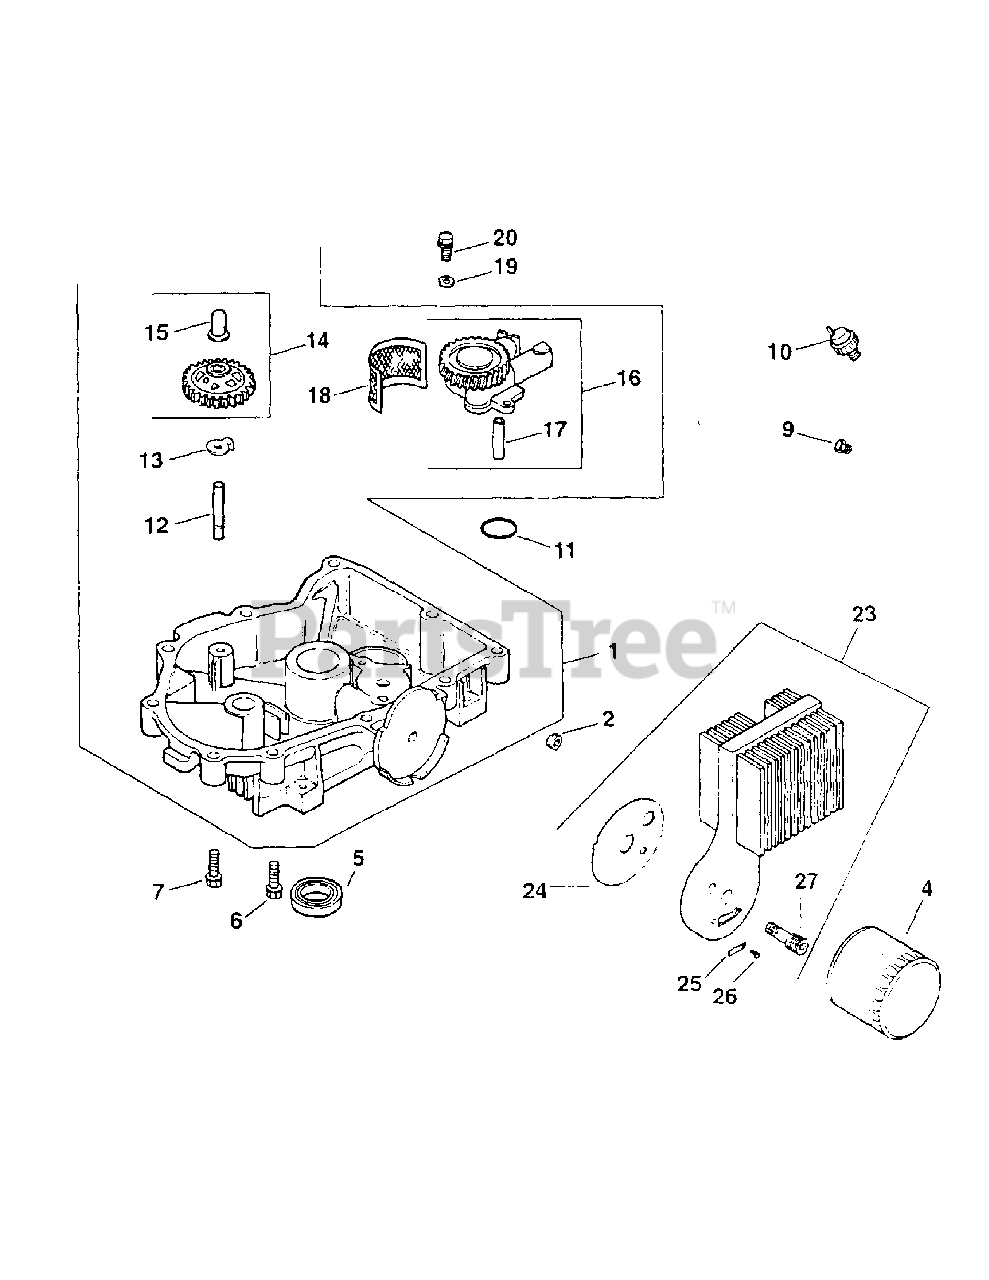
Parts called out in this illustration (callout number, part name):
1	Oil Pan Assembly
2	Plug, Allen Head 3/8"
4	Filter, Oil
5	Seal, Oil (PTO END)
6	Screw, Hex Flange
7	Screw, Hex Flange
9	Plug, Hex Head 3/8"
10	Switch, Oil Pressure
12	Shaft, Governor Gear
13	Tab, Locking
14	Kit, Governor Gear w/Pin
15	Pin, Governor Regulating
16	Oil Pump Assembly
17	Tube, Oil Pickup
18	Screen, Oil Pickup
19	Washer, Plain 6mm
20	Screw, Hex Flange
23	Kit, Oil Cooler
24	Gasket, Oil Filter Adapter
25	Reed, Oil Relief
26	Screw, Hex Cap
27	Nipple, Oil Filter
